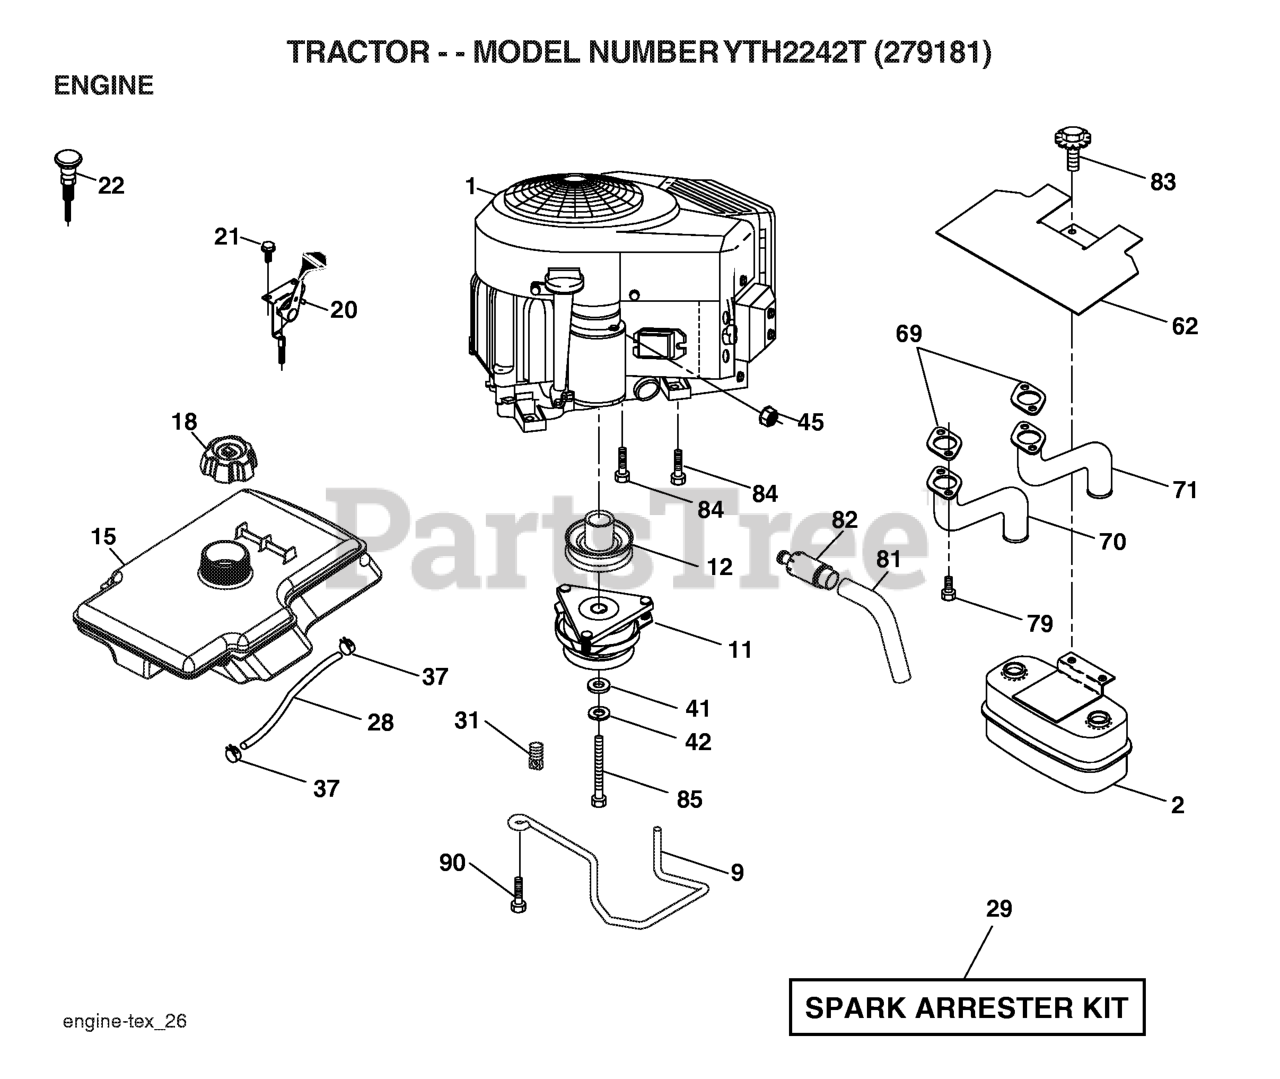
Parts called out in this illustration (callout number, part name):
2	MUFFLER.TWIN.CYL.LOW.TONE
9	KEEPER.BELT.ENGINE.4.2
11	RB.CLUTCH.OGURA.4.4.PD
12	PULLEY.ENGINE.TUFFTORQ
15	TANK.FUEL.2.5.RR.MNT.H
18	CAP.ASM.FUEL.TANK.3"BL
20	THROTTLE CABLE
21	SCREW
22	CONTROL.CHOKE.ERGO.PUSH-IN.BLA
28	LINE.FUEL.64"REAR.EMIS
29	KIT.SPARK ARRESTOR 794945 B&S
37	HOSE CLAMP
42	LOCKWASHER
45	NUT
62	RP SHIELD HEAT MUFFLER
69	GASKET.MUFFLER
70	RP.EXHAUST.TUBE.LH.BS/TWIN
71	EXHAUST.TUBE.RH.BS/TWIN
79	SCREW.SOCKET.HEAD.5/16-18
81	TUBE, DRAIN OIL ASM.
82	PLUG DRAIN OIL EASY
83	BOLT.5/16-18UNCX3/4 W/SEMS.BLK
84	SCREW.3/8-16
85	BOLT HEX 7/16-20X4-1/4"
90	SCREW 3/8-16X1
